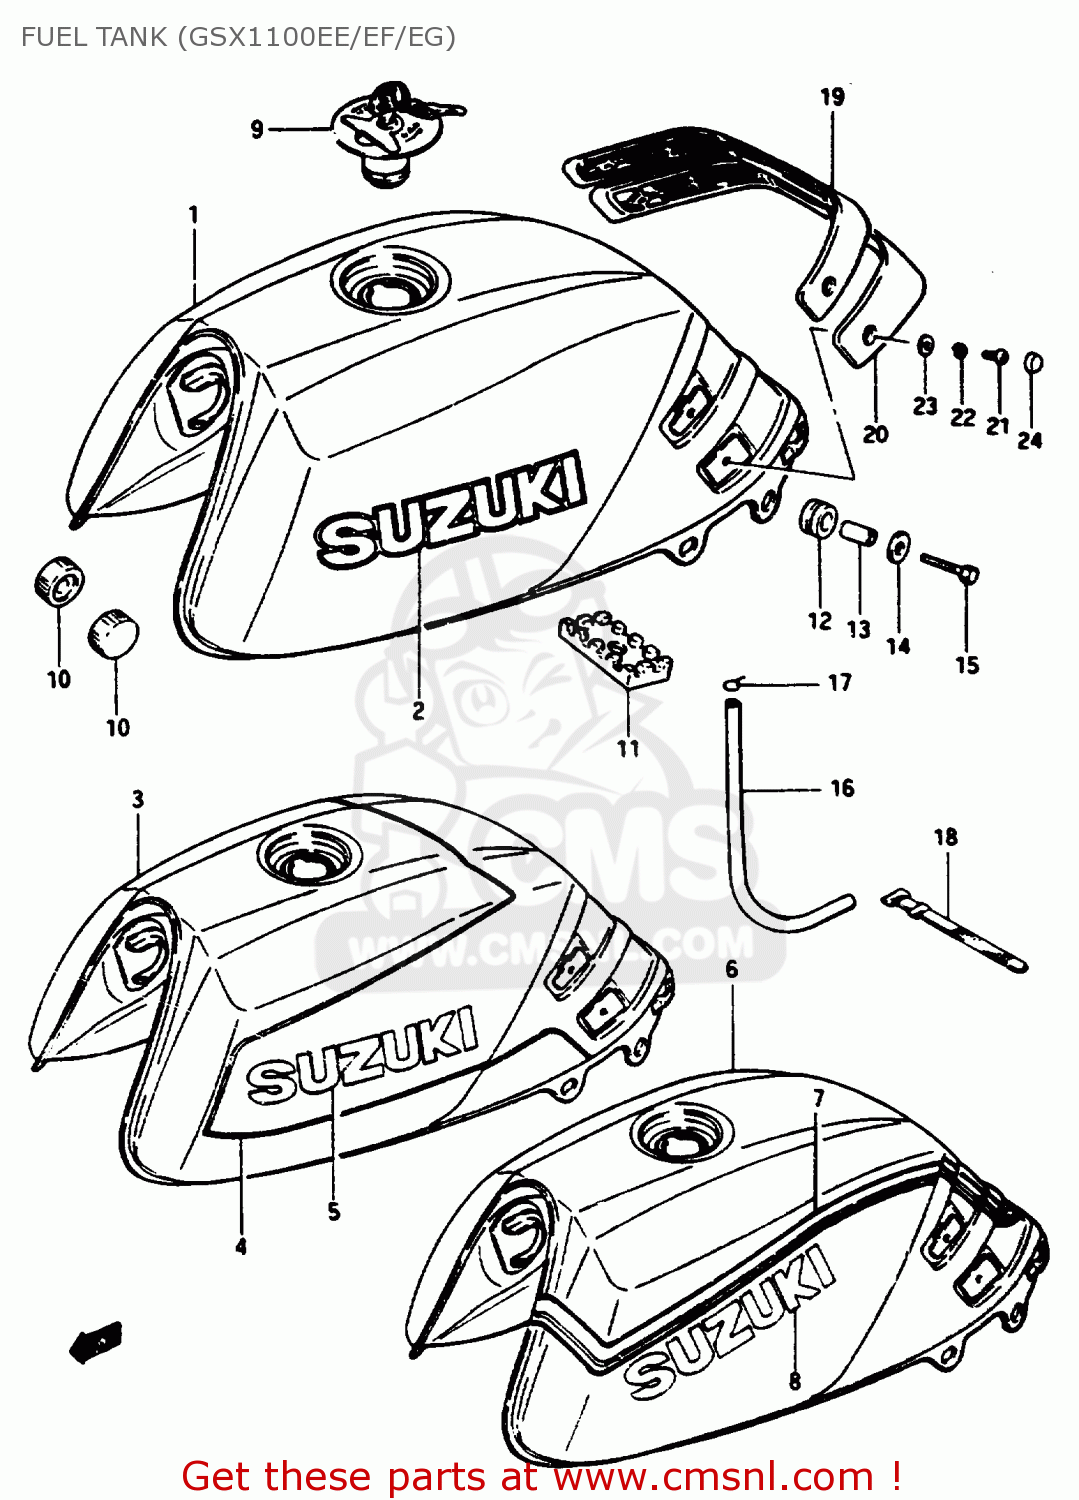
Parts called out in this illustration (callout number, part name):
1	TANK ASSY, FUEL (RED)
2	EMBLEM,FUEL TA
3	TANK, FUEL
4	TAPE SET,FUEL TANK
5	EMBLEM (GOLD)
6	TANK ASSY, FUEL
7	TAPE SET, FUEL TANK
8	EMBLEM,FUEL TANK
9	CAP ASSY,FUEL TANK
10	CUSHION
11	CUSHION,FUEL TANK CTR
12	CUSHION
13	SPACER (6.4X9X20)
14	WASHER (6.5X29X1.6)
15	BOLT 6X30
16	HOSE,FUEL
17	CLIP
18	CLAMP(L:187)
19	KNEE GRIP,FUEL TANK,UPPER
20	GRIP,FUEL TANK KNEE LWR
21	SCREW
22	LOCK WASHER
23	WASHER
24	CAP,KNEE GRIP
